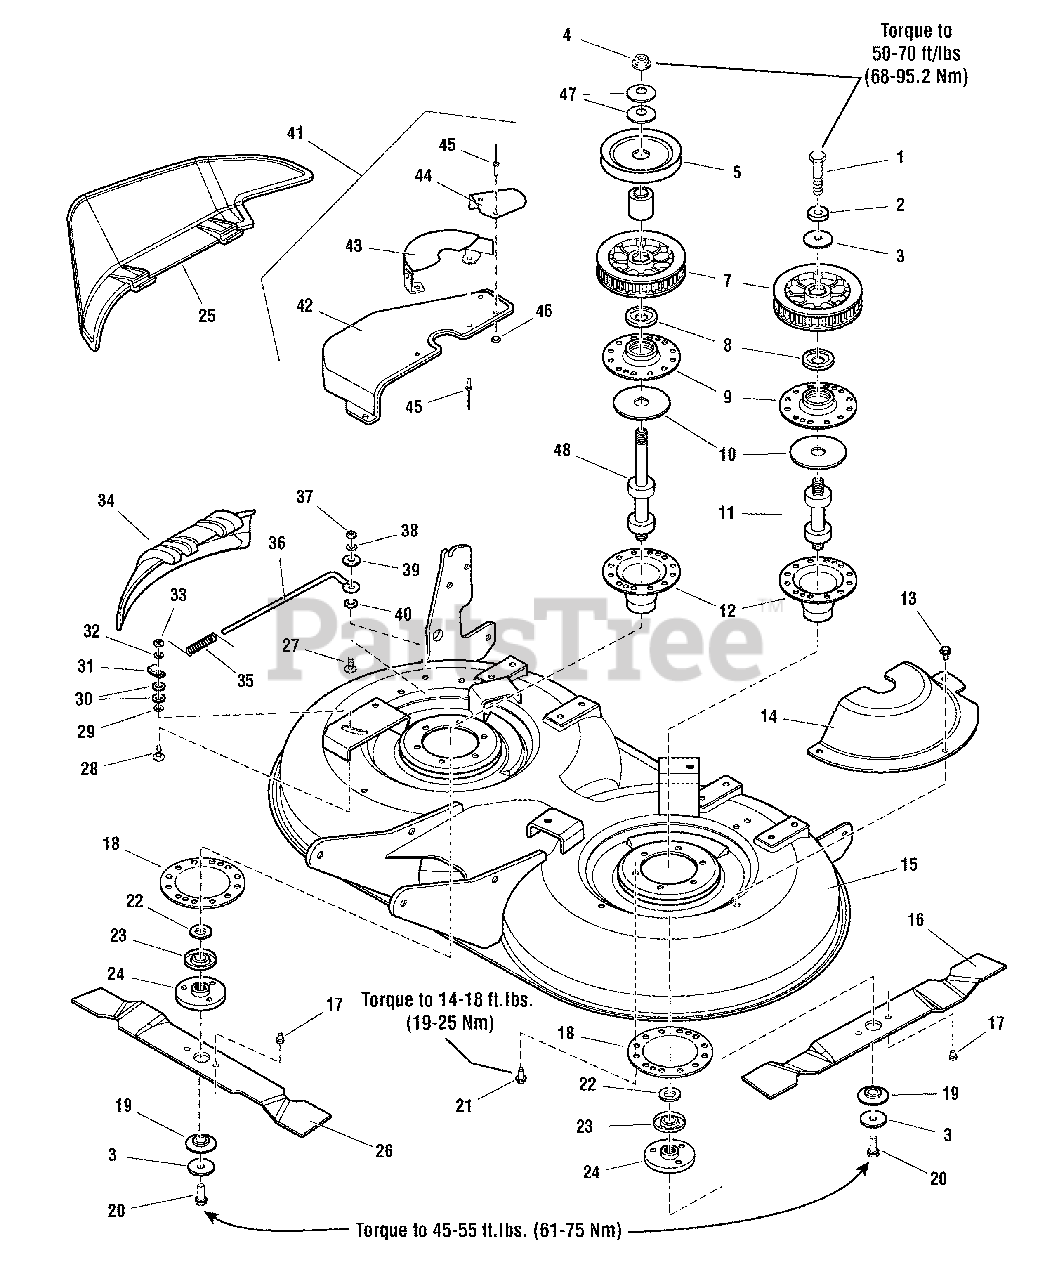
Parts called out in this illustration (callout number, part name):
1	CAPSCREW, Hex Head, 7/16-14 x 2-3/4 G8
2	WASHER, 7/16
3	WASHER, Spring
4	NUT, Hex Flange, 9/16-18
5	PULLEY
6	HUB
7	SPROCKET & FLANGE ASSEMBLY, Riveted, 38 Tooth
8	SHIELD, Arbor Bearing, Upper
9	HOUSING, Arbor Top
10	GASKET, Foam Poly
11	ARBOR SHAFT & BEARINGS ASSEMBLY
12	HOUSING, Arbor Bottom with Lube Fitting
13	CAPSCREW, Taptite Hex Washer Head, 5/16-18 x 3/4
14	COVER, Arbor, LH
15	HOUSING ASSEMBLY, 40", Red
16	BLADE, Mower, LH
17	PIN, Blade
18	ADAPTOR, Arbor
19	WASHER, Spline
20	CAPSCREW, Hex Head, 7/16-14 x 2-1/4 G8
21	CAPSCREW, Taptite Hex Washer Head, 5/16-18 x 1
22	WASHER, Shim
23	SHIELD, Arbor Bearing, Lower
24	ADAPTER, Blade
25	DEFLECTOR, Discharge
26	BLADE, Mower, RH
27	BOLT, Carriage, Short Neck, 5/16-18 x 1
28	CARRIAGE BOLT, 1/4-20 x 7/8
29	NUT, Push
30	WASHER, 1/4
31	CLAMP
32	LOCKWASHER, Spring 1/4
33	NUT, Hex 1/4-20
34	DOOR, Mulching, Black Plastic
35	SPRING, Torsion
36	ROD, Pivot
37	NUT, Hex 5/16-18
38	LOCKWASHER, Spring 5/16
39	WASHER, 5/16
40	NUT, Push
41	COVER ASSEMBLY, Arbor, RH (Includes Ref. Nos. 42 thru 46)
42	COVER, Arbor RH
43	GUARD ASSEMBLY, RH
44	GUARD, Extension
45	RIVIT, Pop
46	WASHER, 3/16 x 3/4 x 1/16
47	WASHER, Bellville, 9/16
48	ARBOR SHAFT & BEARING ASSEMBLY
